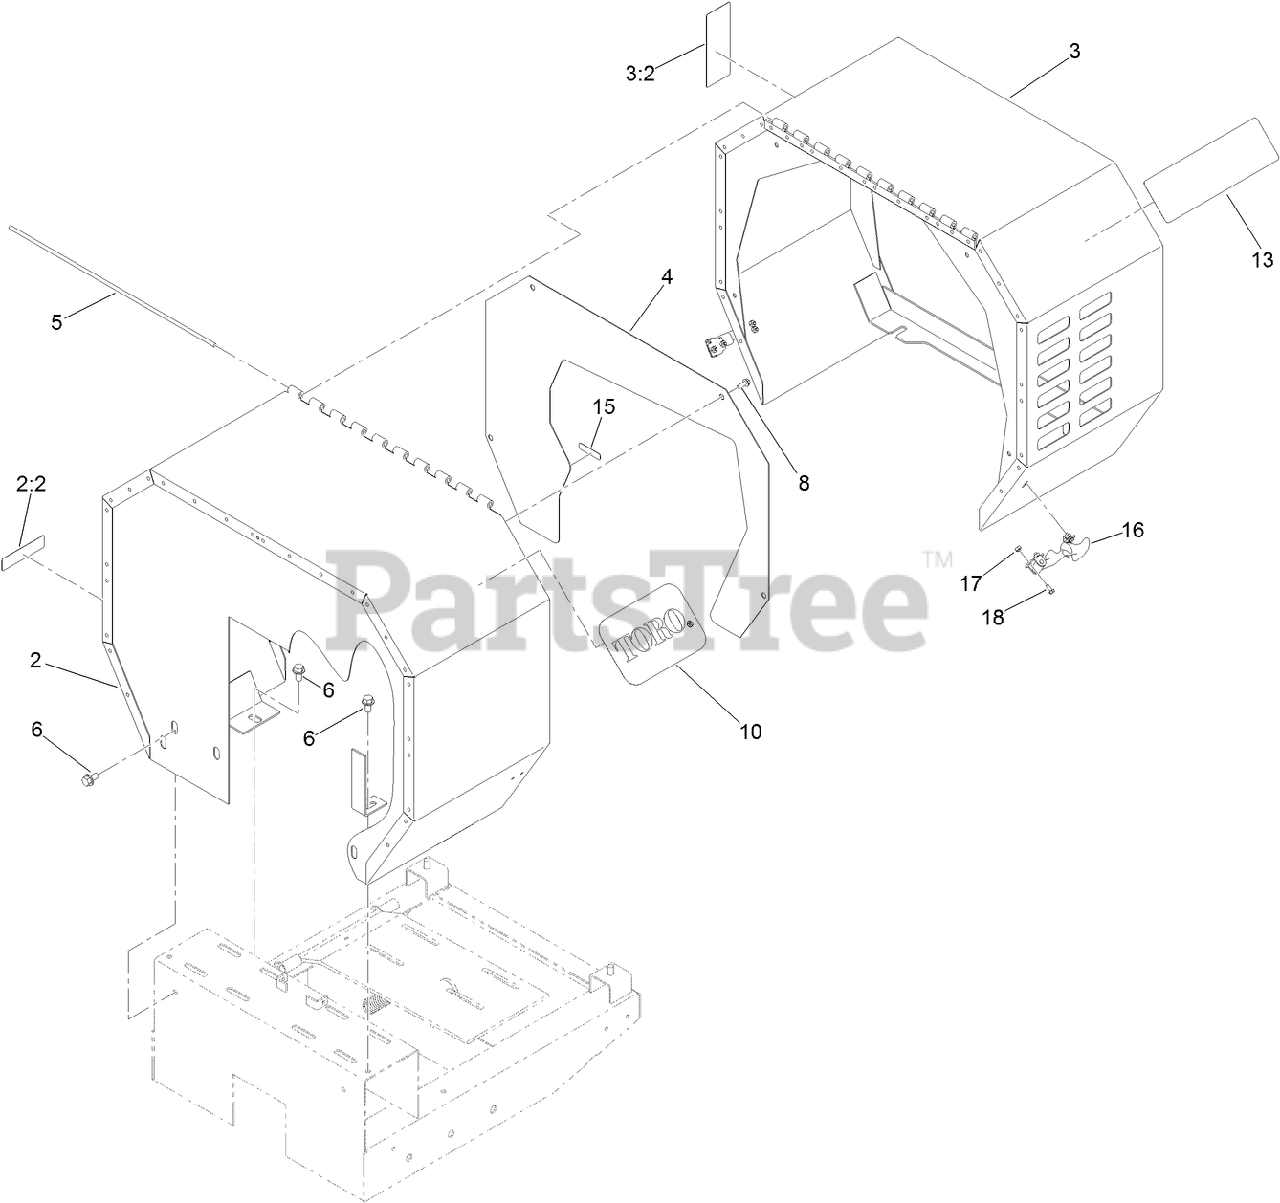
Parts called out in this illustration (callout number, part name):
2	STATIONARY COWL ASM
2:2	DECAL-ARRESTER, SPARK
3	MOVABLE COWL ASM
3:2	DECAL-WARNING
6	SCREW-HWH
8	SCREW-HHF
10	DECAL
15	DECAL-GREASE
16	LATCH-FLEX, DRAW
17	NUT-LOCK, NI
18	SCREW-HWH
